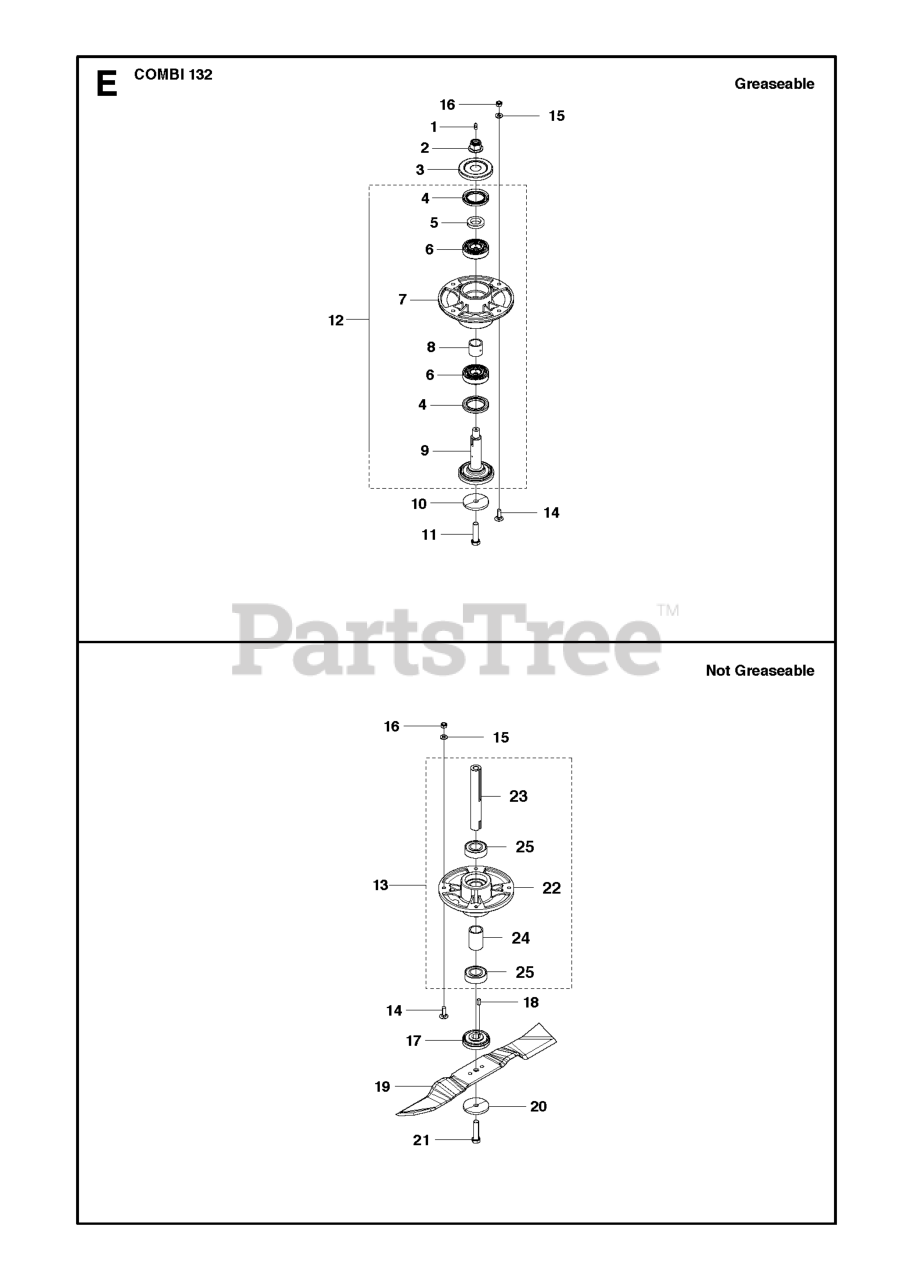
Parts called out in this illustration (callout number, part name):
1	GREASE NIPPLE
6	BALL BEARING 6305 C3
15	WASHER BRB 8.4X17
16	LOCKNUT M8
19	BLADE
22	BEARING HOUSING
25	BALL BEARING
